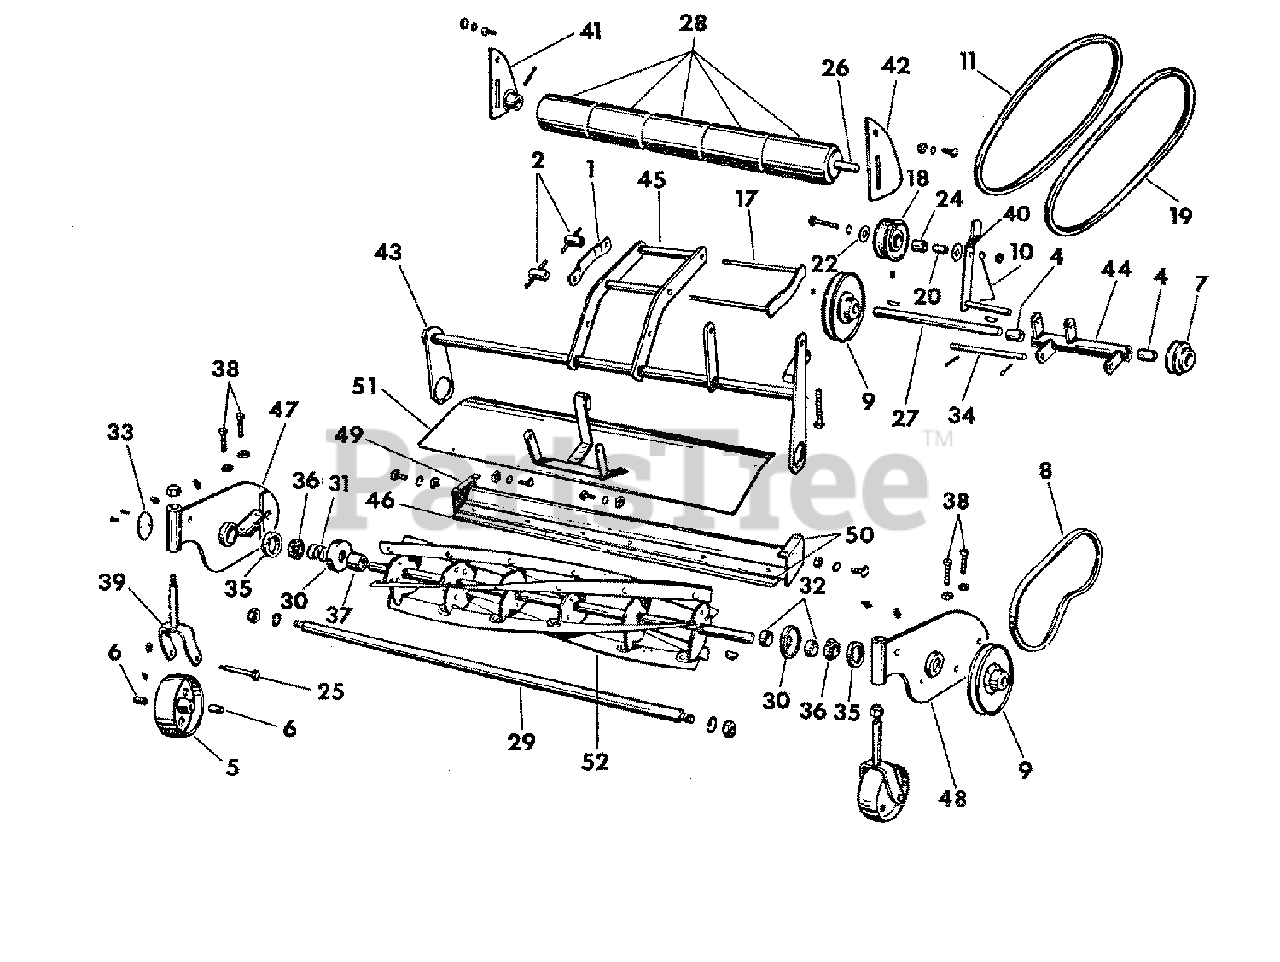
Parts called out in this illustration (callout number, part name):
1	SIDE PLATE, Hitch
2	WING NUT, Complete
4	BUSHING, Bronze
5	CASTER WHEEL, w/ Bearing and Grease Fitting
6	CASTER WHEEL, Bearing
7	REEL, Driver Sheave
8	REEL, Drive Belt, 27" Circumference
9	COUNTER SHAFT & REEL SHEAVE
10	BELT, Holder
11	BELT, 31", 2 H.P. Only
17	CLAMP ASSEMBLY, Hitch
18	PULLEY, Idler
19	BELT, 36", 3 H.P. Only
20	INNER BEARING RACE
22	WASHER, Thrust
24	BEARING, Idler Pulley
25	SPINDLE, Caster Wheel
26	SHAFT, Roller
27	SHAFT, Transmission
28	ROLLER, Hard Wood
29	ROD, Spacer
30	COVER, Bearing
31	SPRING, Bearing
32	SPACER, Bearing, Short
33	CAP, Bearing
34	PIN, Hinge
35	CAP, Bearing, Timken
36	CONE, Bearing, Timken
37	SPACER, Bearing, Long
38	SCREW, Blade Adjusting
39	FORK ASSEMBLY, Caster
40	LEVER ASSEMBLY, Idler
41	BRACKET, Roller, R.H.
42	BRACKET, Roller, L.H.
43	ARM ASSEMBLY, Push, R.H.
44	BEARING BRACKET, w/ Bushings & Grease Fitting
45	ARM ASSEMBLY, Push, LH. Push Arm
46	BLADE
47	FRAME ASSEMBLY, Lawn Mower, R.H.
48	FRAME ASSEMBLY, Lawn Mower, L.H.
49	BAR ASSEMBLY, Cutter
50	BAR ASSEMBLY, Cutter, w/ Blade
51	GUARD ASSEMBLY, Grass
